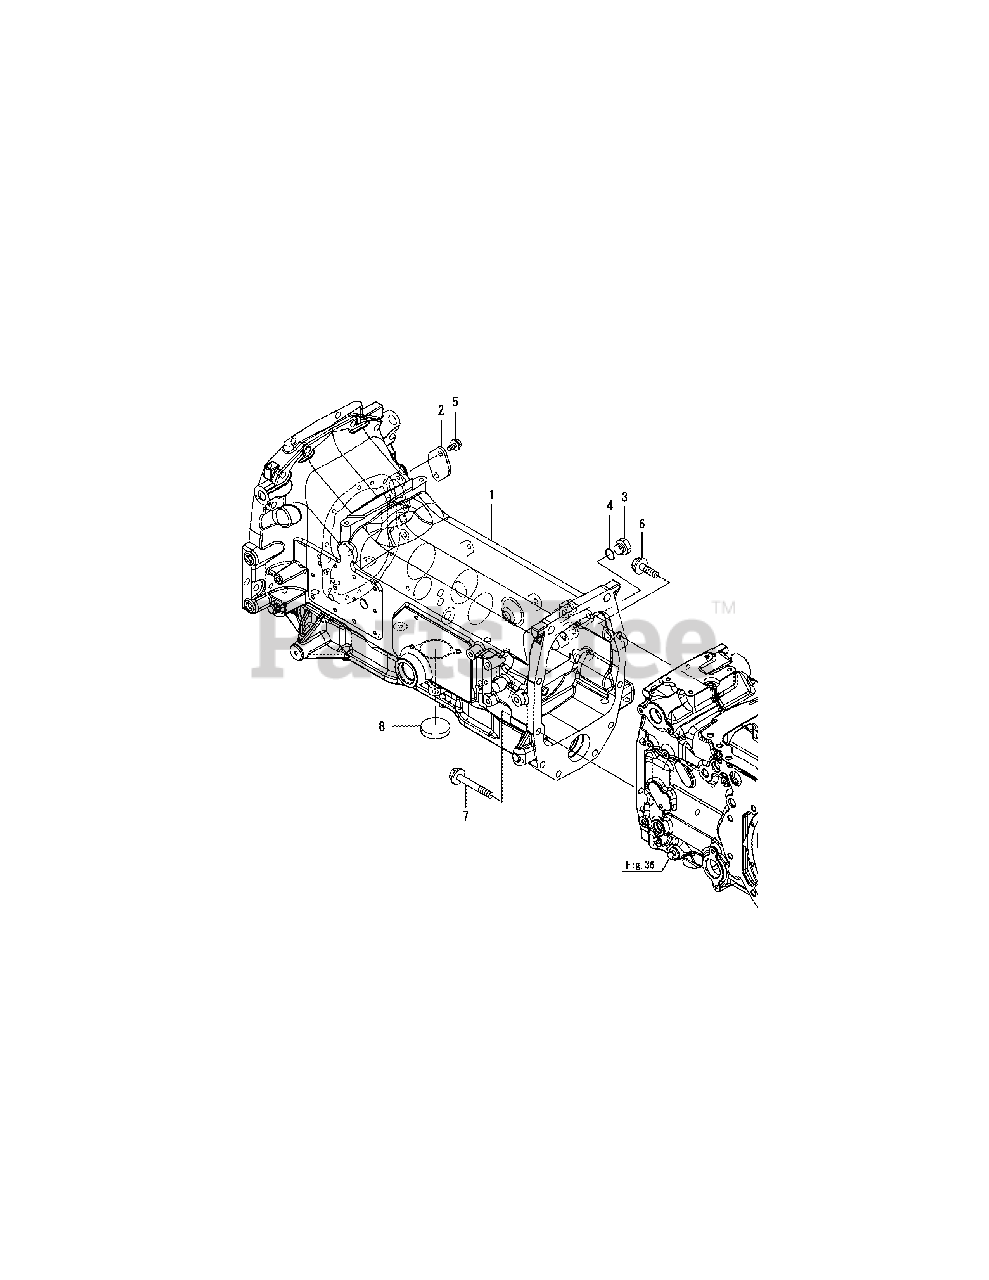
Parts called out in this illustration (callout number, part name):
1	HOUSING, CLUTCH
3	PLUG 3/4-16UNF
5	BOLT M 8X 16 PLATED
6	BOLT, M12X 40 PLATED
